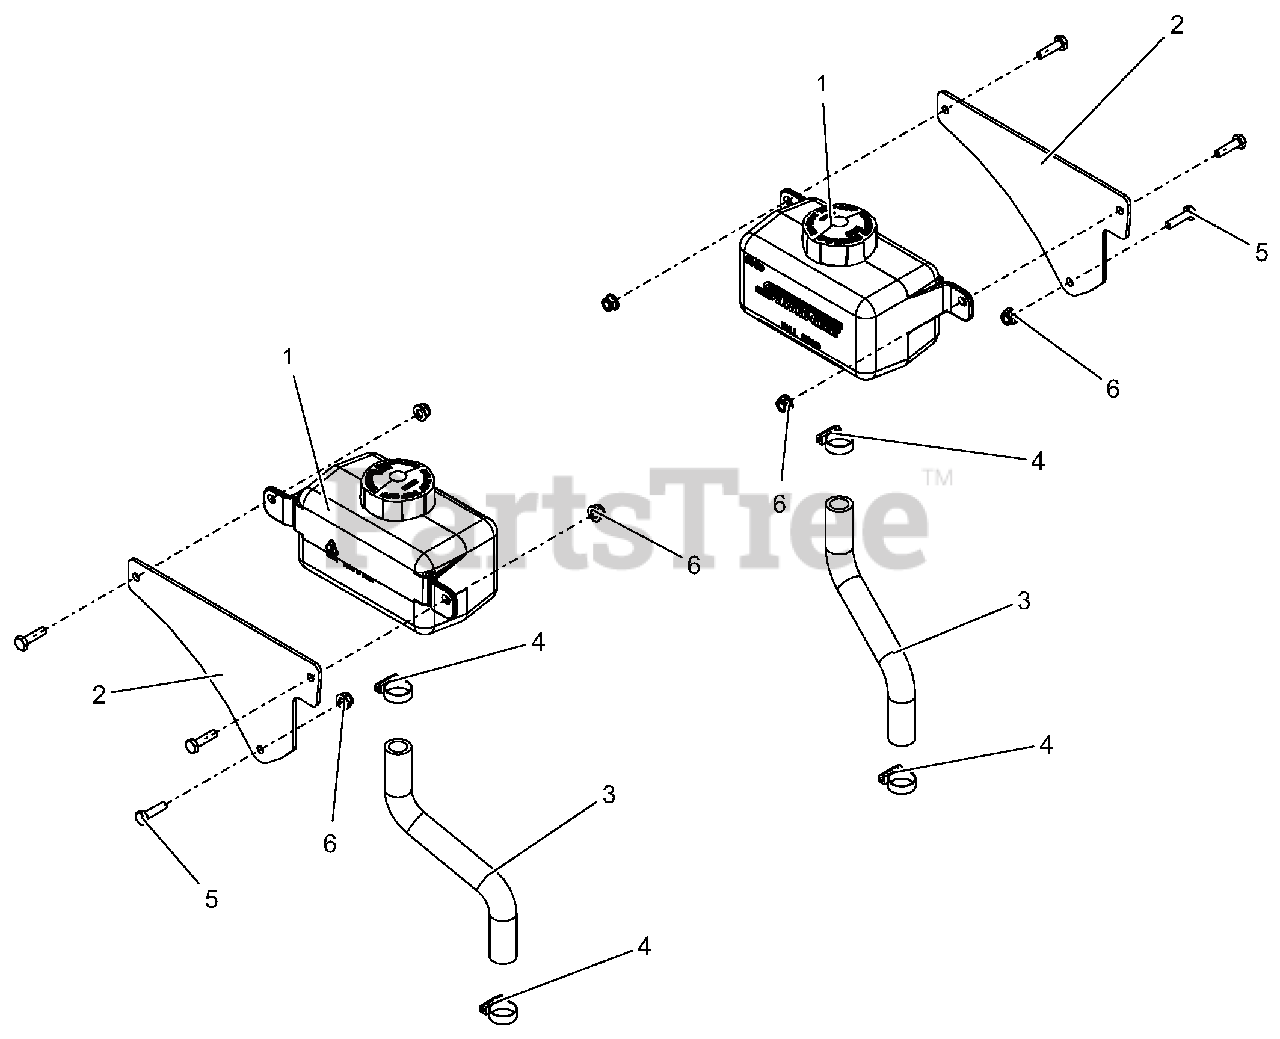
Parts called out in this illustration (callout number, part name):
1	TANK, HYD 1000ML
2	PLATE, HYDRO OVERFLOW TANK MTG
3	HOSE, HYDRO OVERFLOW
4	CLAMP, .88 DIA HOSE
5	BLT-HEX .25-20X1.00 GR5 YWZC
6	NUT-LK-NYL-FLG .25-20 YWZC
